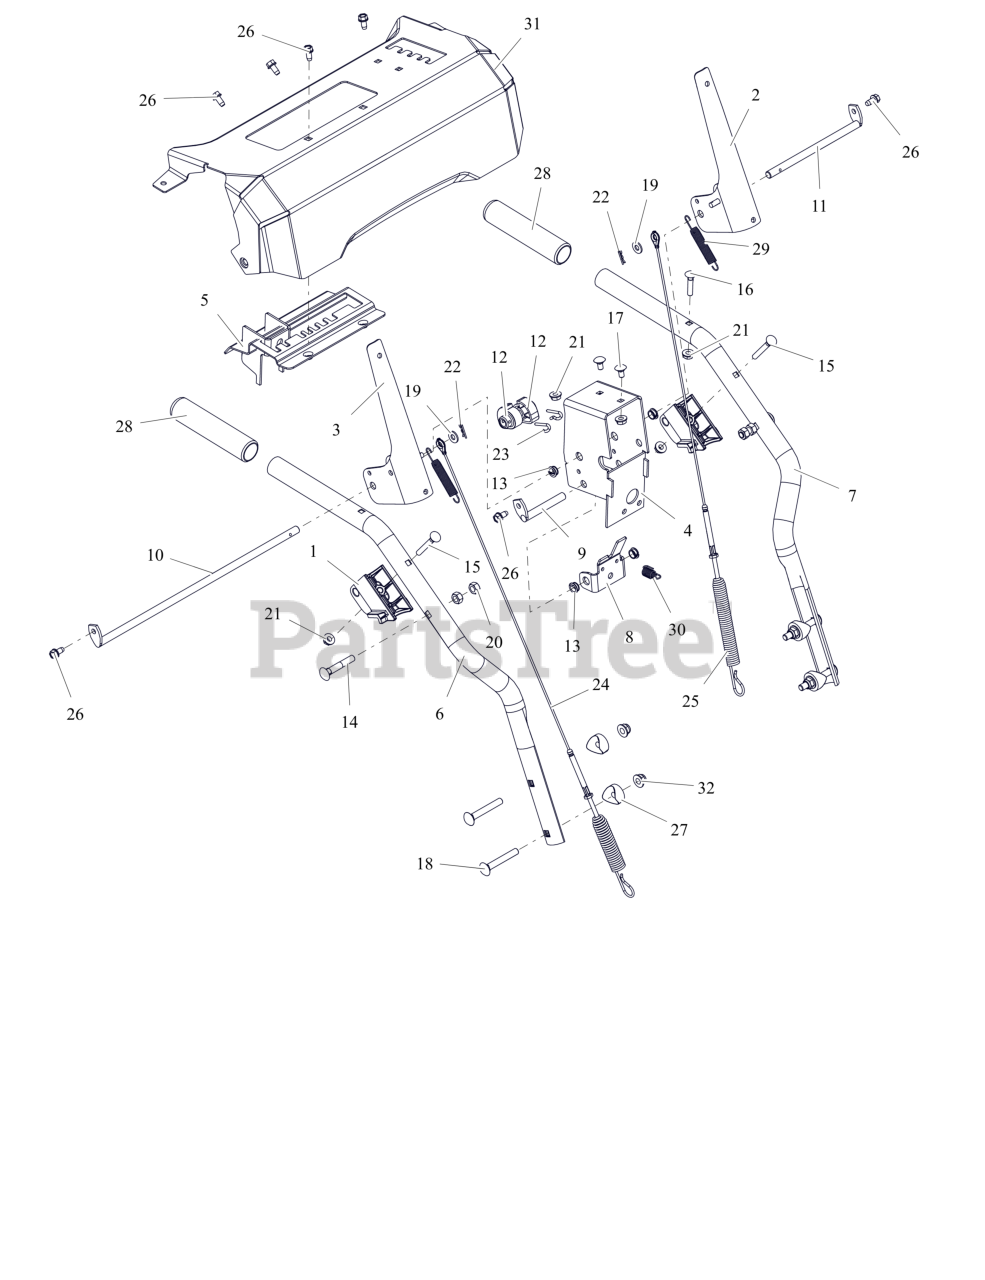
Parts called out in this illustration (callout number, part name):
1	BLOCK, CLUTCH PADDLE
2	LEVER, CLUTCH-LH
3	LEVER, CLUTCH-RH
4	WELDMENT, BRACKET INTERLOCK
5	WELDMENT, DETENT PLATE-COMPACT
6	HANDLEBAR, UPPER - RH
7	HANDLEBAR, UPPER - LH
8	BRACKET, INTERLOCK ARM
9	ROD, PIVOT - INTERLOCK
10	ROD, PADDLE MOUNT - LONG
11	ROD, PADDLE MOUNT - SHORT
12	CAM, INTERLOCK
13	BUSHING, POLYLINER-.38 SNAPIN
14	BLT-RDHDXLSQNK .31-18X2.0 G5YZ
15	BLT-RDHDXLSQNK .25-20X2.0 G5YZ
16	BLT-RDHDXLSQNK.25-20X1.25 G5ZC
17	BLT, RHSN .25-20X.500 G5 ZCC
18	BLT-RHSN.31-18X2.25 G5 TBZ 120
19	WSHR,FLT .281X.625X.065 ZCC
20	NUT,LK-CTR .31-18 GA ZCC
21	NUT-LK-CTR-FLG .25-20 ZC120
22	PIN, HAIR #178 .06X.77 ZCC
23	PIN, SPRING CLIP
24	CABLE, AUGER (DELUXE & PRO)
25	CABLE, UPPER TRACTION
26	SCR-TAP .25-20X.50 HWH ZCC
27	SPACER, HANDLEBAR
28	GRIP, HANDLEBAR
29	SPRING, EXTENSION
30	SPRING-EXT .047X.438X1.45
31	PANEL, DASH - SMALL PB W/DECALS
32	NUT-NYL-FLG.31-18 GF TBZ 120WR
